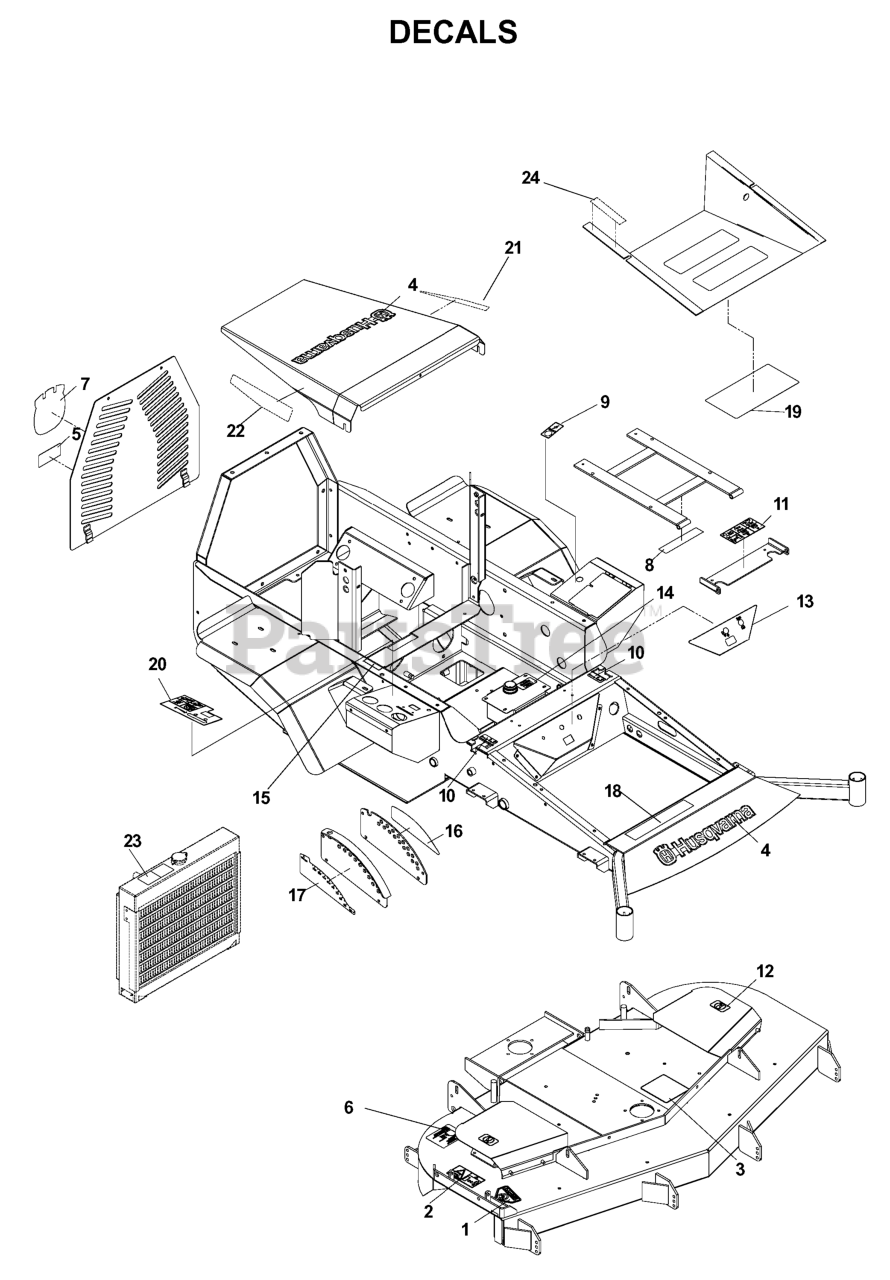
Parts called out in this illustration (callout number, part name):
1	DECAL, CPSC
2	DECAL, EURO SEVERING
3	DECAL, BELT ROUTING
4	DECAL, HUSQVARNA 17.5"
5	DECAL, BELT DRIVE
6	DECAL, ANTI SCALP
7	DECAL, LGE CROWN 7X6"
8	EURO DECAL-BATTERY WARNIN6
9	DECAL, 12V
10	DECAL, MOTION CONTROL
11	DECAL, EURO WARNING
12	DECAL, NO STEP
13	DECAL, FRONT CONSOLE
14	DECAL, MOBIL 1
15	FUEL VALVE DECAL
18	DECAL, MODEL BZE6127D
19	DECAL, SERVICE
20	DECAL, RT CONSOLE
21	DECAL, 34 TURBO LH
22	DECAL, 34 TURBO RH
23	DECAL, HOT
